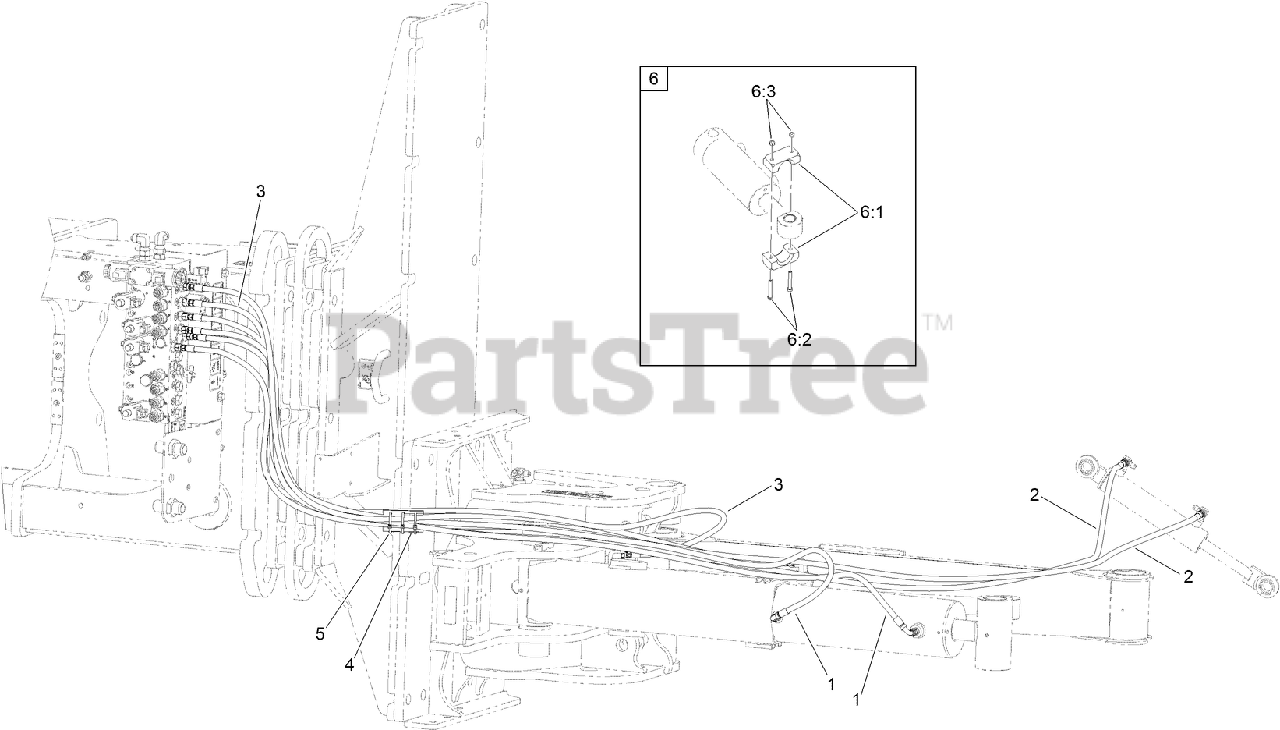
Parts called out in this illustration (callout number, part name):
1	HYD HOSE ASM
2	HYD HOSE ASM
3	HOSE ASM
4	PROTECTOR-HOSE
5	TIE-CABLE
6	2.00 INCH STOP BLOCK ASM
6:1	BLOCK-STOP
6:2	SCREW-HH
6:3	NUT-HEX
